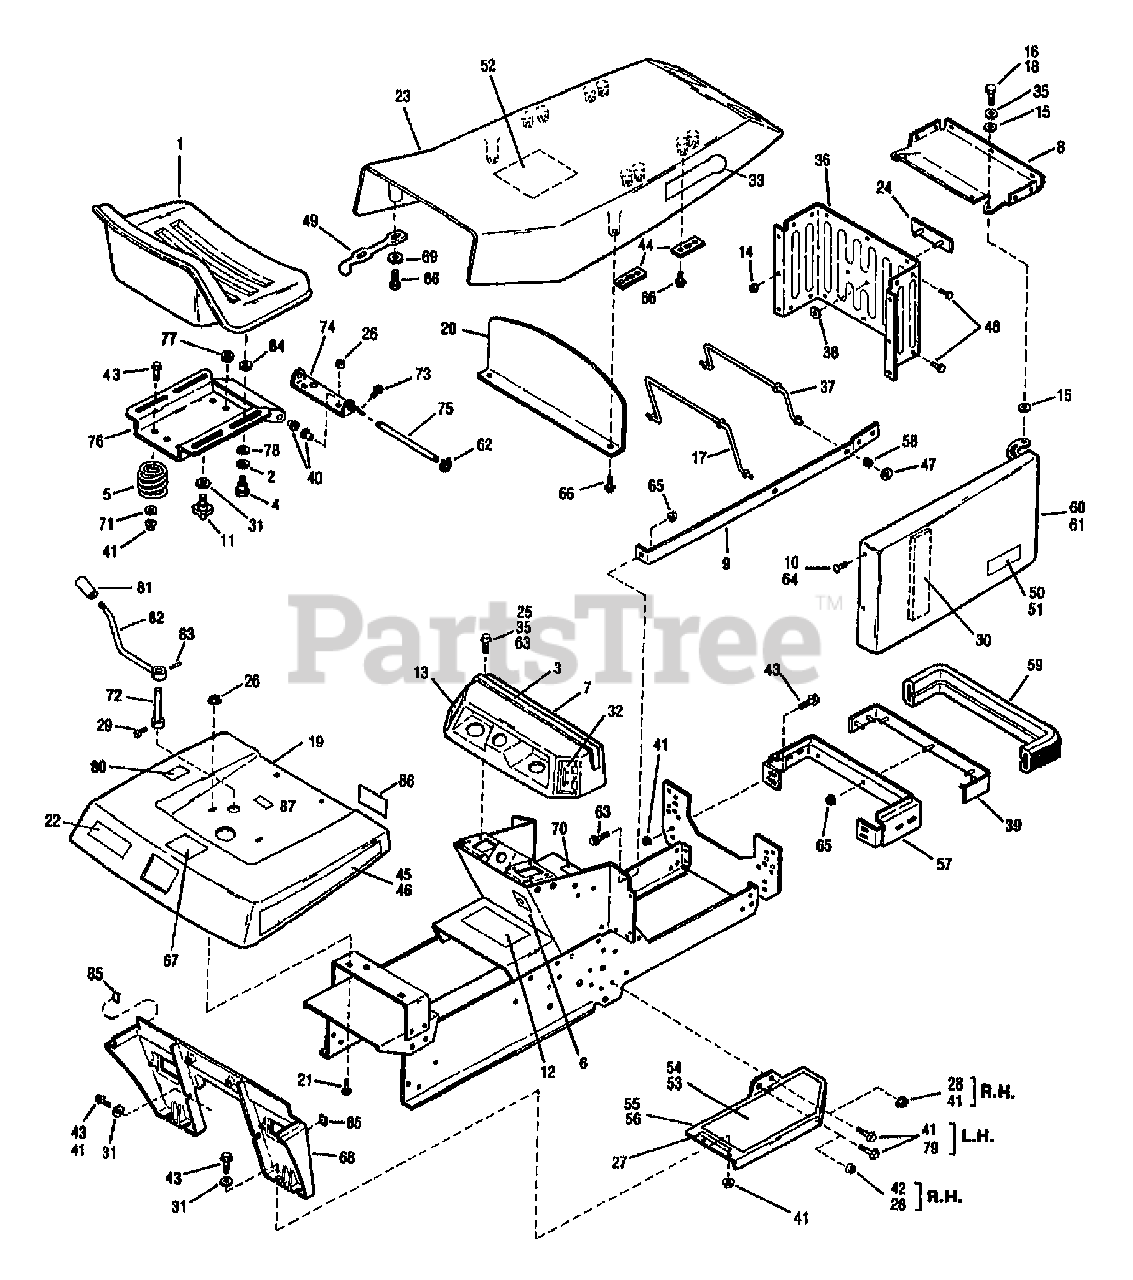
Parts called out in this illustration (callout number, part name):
2	WASHER-1.06X.51X.09 NYLON
3	PAD-HOOD
4	SCR-SHLDR 3/8-16X.25 G5ZP
5	SPRING-COMPRESSION
6	DECAL-IGNITION
7	PANEL-INST
8	CAP-GRILLE
9	SUPPORT
10	NUT-SPEED #10
12	DECAL-OPERATING INST
13	DECAL-CHOKE
14	NUT W/LKWASHER 10-24 ZP
15	WASHER
16	SCR-HH 1/4-20X.75 G5 ZP
17	LINK-HINGE
18	NUT-HT LK 1/4-20
20	BAFFLE-HOOD
21	BOLT-CARR 5/16-18X.63 ZP
22	DECAL-LOGO FENDER
23	HOOD-TRACTOR
24	PLATE-LOGO
25	NUT-HF/LK 1/4-20 ZP
26	NUT-HFLK 5/16-18 ZP
27	CUSHION
28	SCR-HH 3/8-16X.75 G5 ZP
29	SCR-SQHD 1/4-20X1/2 GR5 (13062 ONLY)
30	BLOCK-SEALING
31	WASHER-.986X.437X.083 ZP
32	DECAL-THROTTLE
33	DECAL-LOGO
35	WASHER-FLAT 1/4 SAE
36	GRILLE-TRACTOR
37	LINK-HINGE
38	NUT-PUSH
39	ASSM-BUMPER STRAP
40	BEARING-FLANGE
41	NUT-HFLK 3/8-16 ZP
42	SCR-TRUSS HD 5/16-18X.62
43	SCR-HFLK 3/8-16X1.00 ZP
44	RETAINER-HINGE LINK
45	DECAL-FENDER RH {13060}
45	DECAL-FENDER RH {13062}
46	DECAL-FENDER LH {13060}
46	DECAL-FENDER LH {13062}
47	RETAINER
48	RIVET-POP
49	LATCH-RUBBER
50	DECAL-SIDE COVER LH
51	DECAL-SIDE COVER RH
52	DECAL-SERVICE INST
53	PAD-FOOTREST LH
54	PAD-FOOTREST RH
55	FOOTREST-LH
56	FOOTREST-RH
57	ASSM-GRILLE SUPT
58	GROMMET
59	BUMPER-EXTRUSION
60	COVER-SIDE LH
61	COVER-SIDE RH
62	RING-RET."E" .300 ID
63	SCR-HH 1/4-20X.625
64	SCR-TRUSS #10-24 X 5/8
65	NUT-HF/LK 1/4-20 ZP
66	SCR-SEMS MACH
67	DECAL-FUEL
68	SUPT-RUNNING BOARD
69	DECAL-FUEL
70	DECAL-WARNING
71	WASHER-FLAT 1.25X.406X.179
72	SHAFT-SHIFT LEVER
73	SCR-HFLK 5/16-18X.75 ZP
74	BRACKET
76	ASSM-SEAT SUPPORT
78	WASHER-BOW .74X.52X.01
80	DECAL-TWO SPEED {13062}
81	KNOB-SHIFT LEVER {13062}
82	LEVER-SHIFT {13062}
83	PIN-ROLL .188X1.0 {13062}
84	WASHER-FLAT
85	BUTTON-RUBBER
86	DECAL-U.S.A.
87	DECAL-SOUND LEVEL
